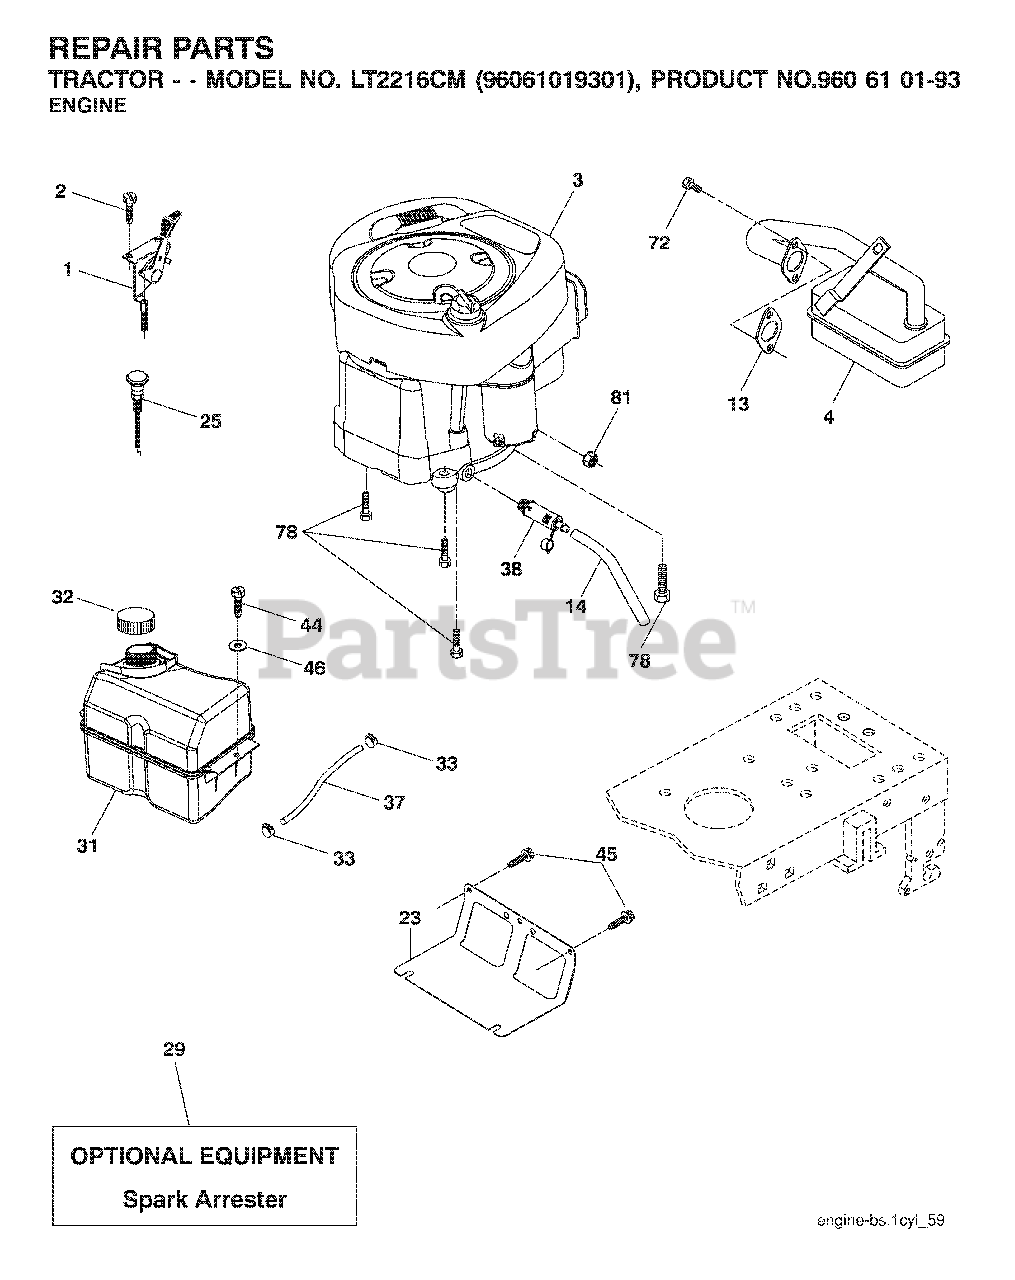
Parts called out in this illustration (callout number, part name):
1	CONTROL TH/CH FLAG
2	SCREW
13	REPL BY 532 27 22-93
14	TUBE, DRAIN OIL ASM.
23	SHEILD.BROWNING.DBR.GUARD
29	ARRESTER SPARK (OPTIONAL)
31	TANK FUEL
32	FUEL CAP
33	HOSE CLAMP
37	LINE.FUEL.20
38	PLUG DRAIN OIL EASY
44	SCREW HEXWSHR 1/4-20X3/4
45	SCREW, 3/8-16X3/4
72	SCREW.SOCKET HD.5/16-1
78	SCREW.3/8-16
81	NUT
